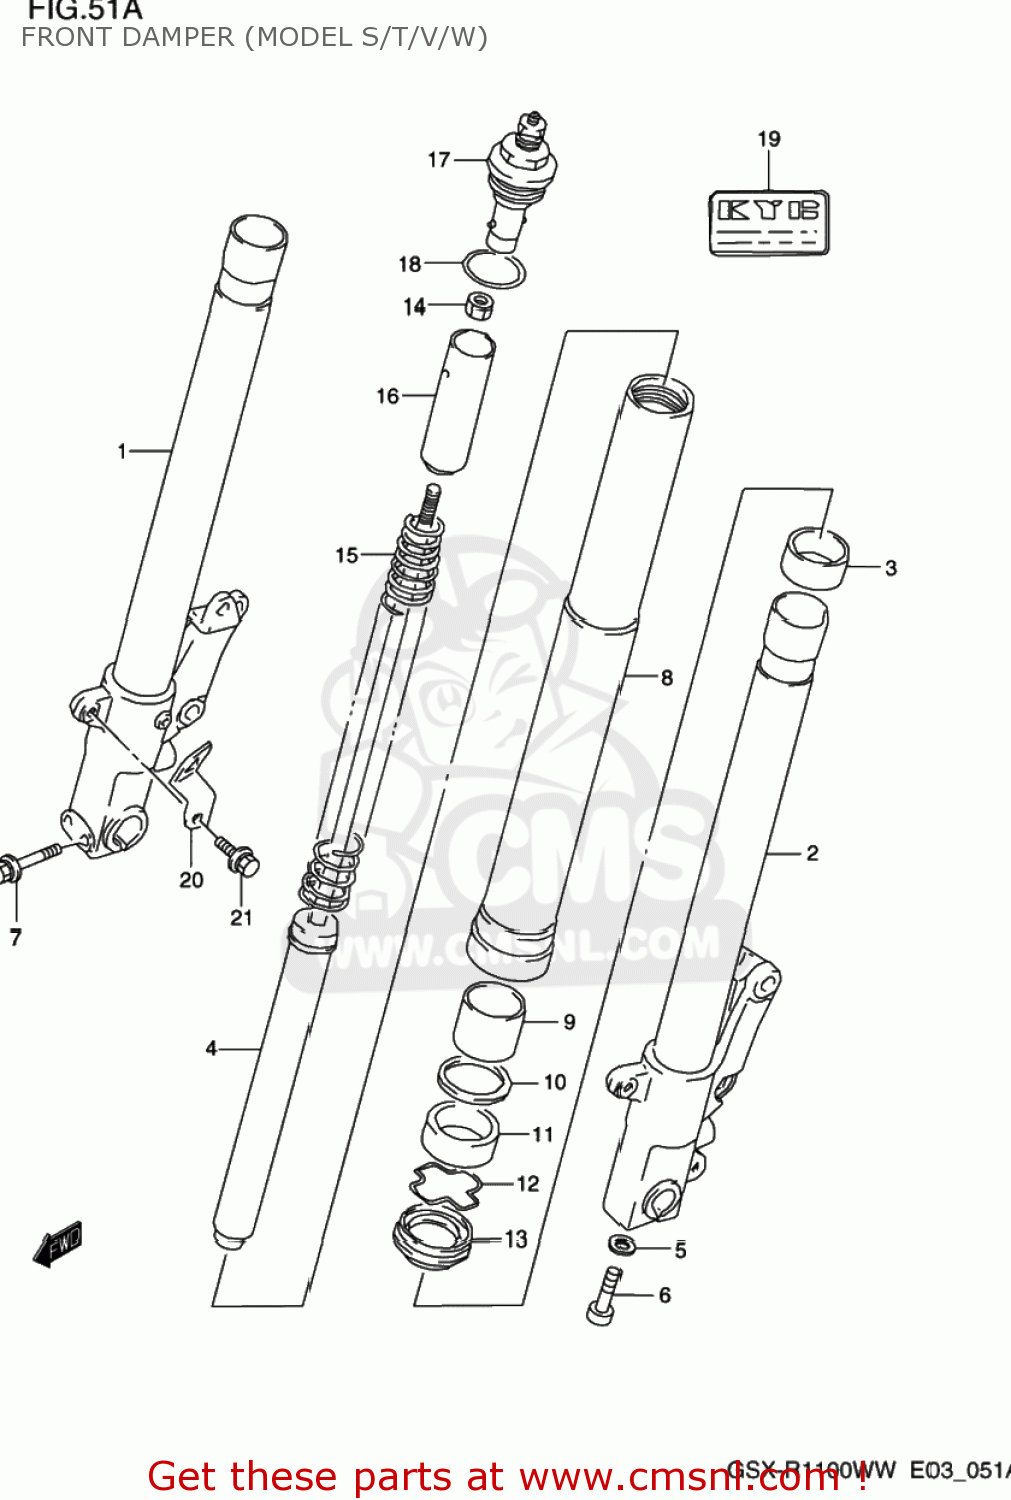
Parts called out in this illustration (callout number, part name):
1	TUBE,INNER,R
2	TUBE,INNER,L
3	PISTON
4	CYLINDER ASSY
5	GASKET,CYLINDER (NAS)
6	BOLT,OIL LOCK PIECE,12X22
7	BOLT
8	TUBE,OUTER
9	METAL,SLIDE
10	WASHER
11	SEAL,OIL
12	RING,STOPPER
13	SEAL,DUST
14	NUT,ROD
15	SPRING,MAIN
16	SPACER,SPRING
17	BOLT ASSY,FORK
18	O RING
19	LABEL
20	PLATE,FRONT FENDER,LEFT
21	BOLT
